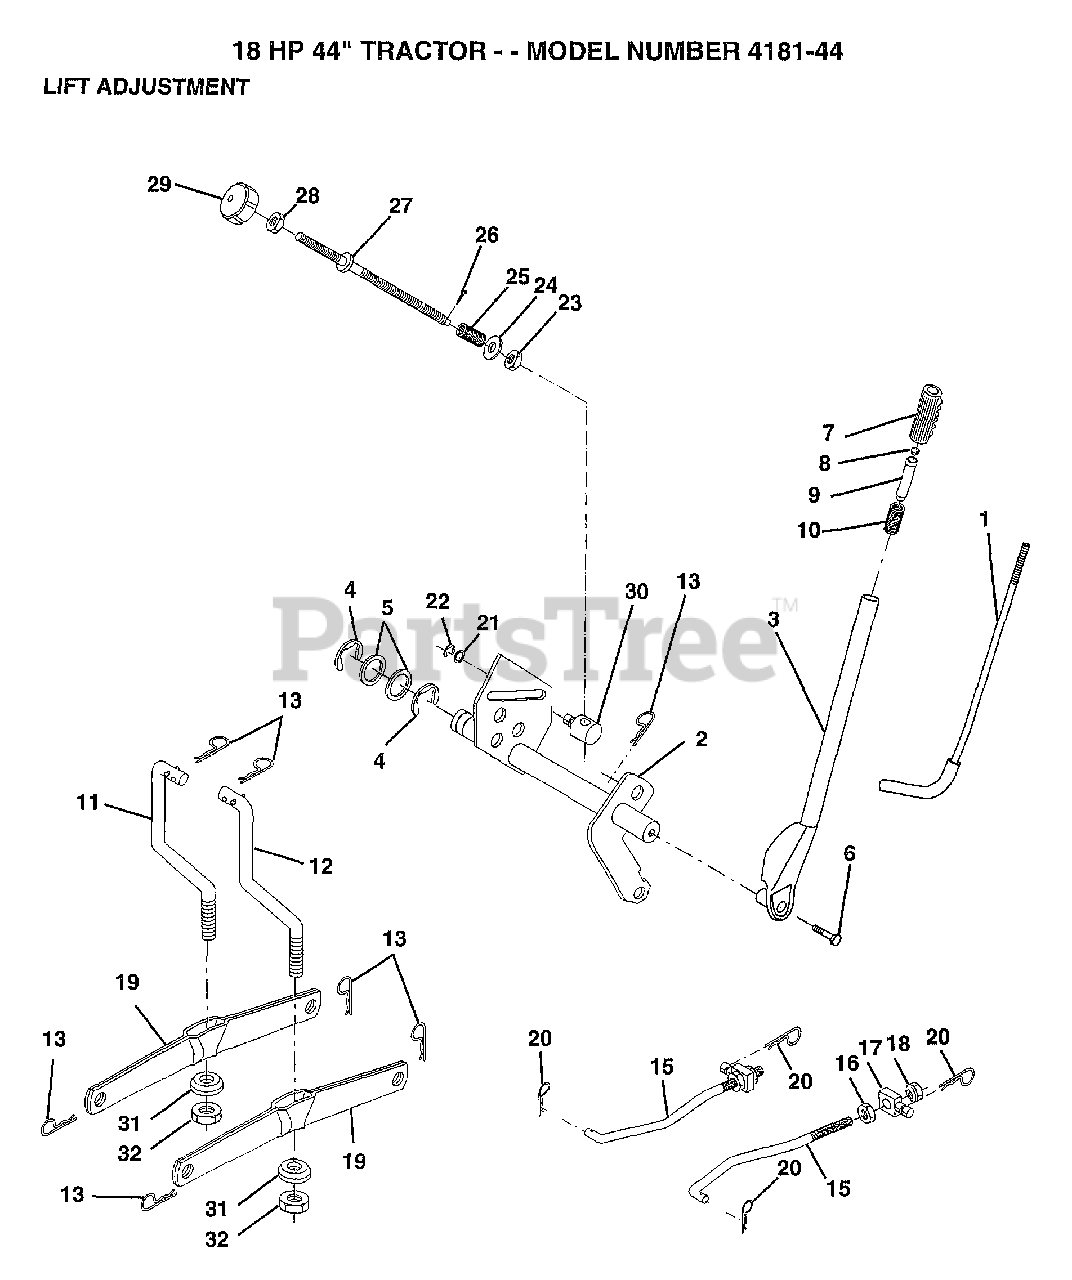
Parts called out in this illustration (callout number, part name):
1	LEVER ROD LT
2	SHAFT LIFT W/IND
4	E-RING
5	WASHER
6	"BOLT,HEX"
7	GRIP
10	SPRING T
15	LINK.FRONT
16	NUT
17	TRUNION
18	NUT.LK.W/WSH.1/2.
19	ARM SUSP REAR
20	RETAINER.SPRING
21	WASHER
22	KLIP RING
23	NUT T
24	WASHER
25	SPRING T
27	ROD LIFT LT
28	NUT
29	KNOB INF 3/8-16
30	TRUNION LT
31	BEARING PVT LH
32	NUT.CROWNLOCK.3/8
